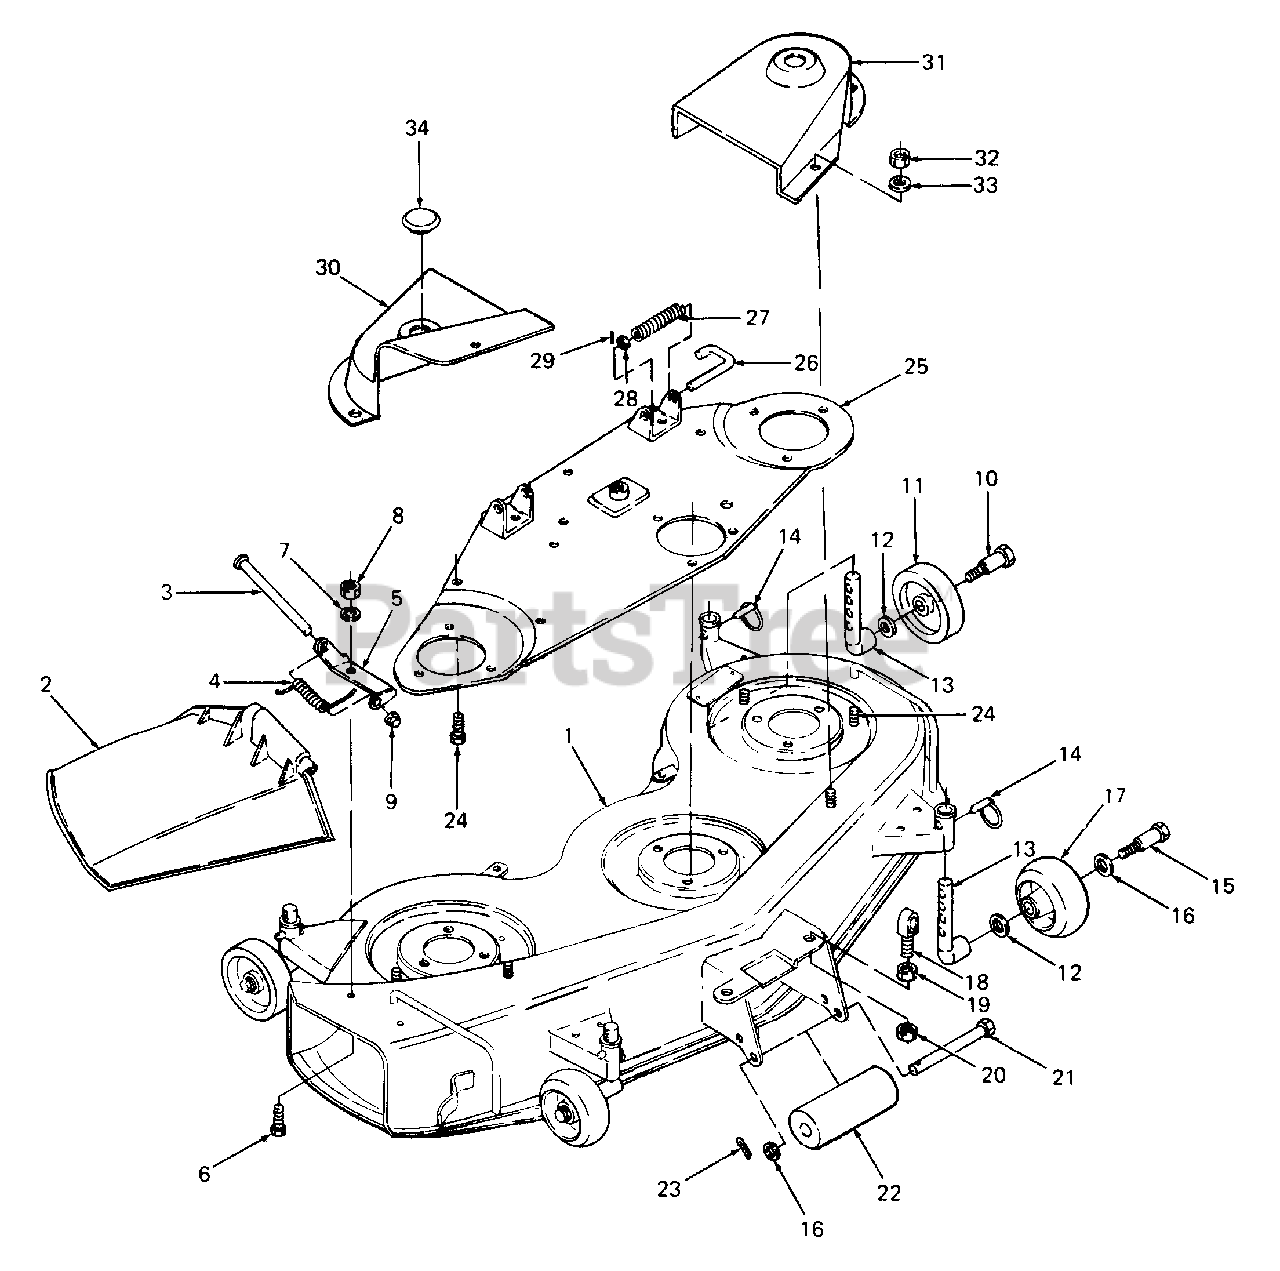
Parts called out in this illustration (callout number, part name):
2	Chute Kit w/Graphic
3	Pin, Hinge, 0.25 Dia X 6.75 Lg
4	Spring, Torsion
5	Bracket, Hinge Mtg.
6	Screw, Truss Machine, 1/4 - 20 X .75 Lg, Phillips
7	Washer, Lock, 1/4 Dia
8	Nut, Hex, 1/4 - 20 GR5
9	Nut, Cap Speed
10	Screw, Shoulder
11	Wheel, Gauge, 5 in. Dia
12	Washer, Bell
13	Axle, Deck
14	Pin, Clevis w/Detent Ball
15	Screw, Shoulder
16	Washer, Flat, .510 X 1.0 X .06 Thk
17	Wheel, Ball w/Fitting, 5 in. DIA
18	Hanger, Front Mower Support
19	Nut, Hex Jam, 5/8-11 GR5
20	Nut, Hex Jam Lock, 5/8-11 GR5
21	Pin, Clevis, 1/2 Dia X 7.0 Lg
22	Roller, Front
23	Pin, Cotter, 3/16 Dia X 1.0 Lg
24	Screw, Hex Cutting, 5/16-18 X.75 Lg
25	Plate, Adapter
26	Pin, Mower Support
27	Spring, Compression
28	Washer, Flat, .531 X .930 X .050 Thk
29	Pin, Spirol Spring, 3/16 Dia X.75 Lg
30	Cover, Belt RH
31	Cover, Belt LH
32	Nut, Hex, 5/16-1 8 GR5
33	Washer, Flat, .34 X .88 X .062 Thk
34	Plug, Button
